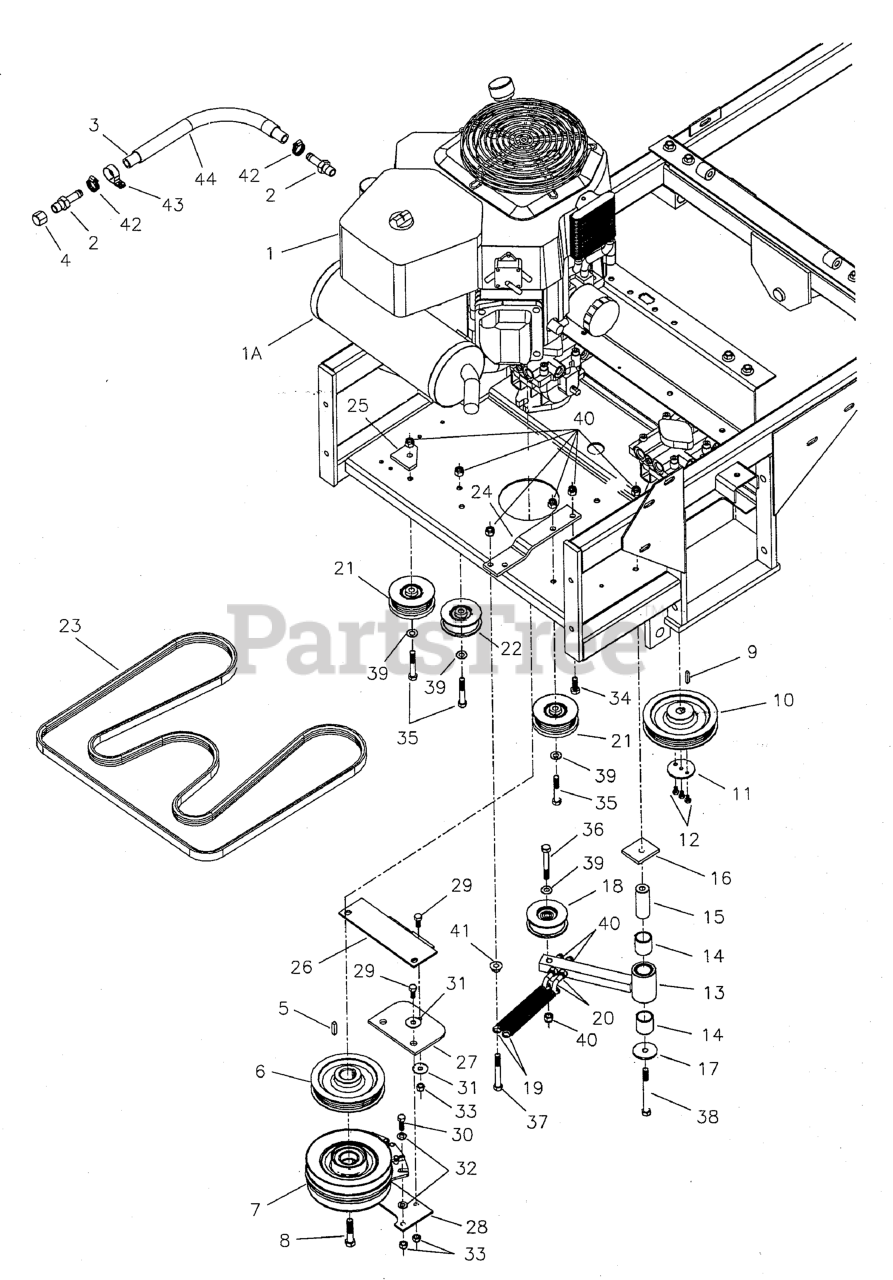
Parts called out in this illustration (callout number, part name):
1A	MUFFLER, Kohler
2	FITTING, 3/8NPT-1/2" Hose, Straight
3	HOSE, 16" Long
3	HOSE, 14"
4	CAP, 3/8 NPT
5	KEY, 1/4 SQ. X 1
6	PULLEY, Crankshaft
7	CLUTCH, Electric
7	CLUTCH, ISZKAV23
8	CRANKSHAFT BOLT, 7/16 x 2
8	CRANKSHAFT BOLT, 7/16 x 1-3/4
9	KEY, 5MM SQ. x 25MM w/ Round Ends
10	PULLEY, Pump Drive
11	WASHER, Pulley Retaining
12	BOLT, M6 x 10MM
13	IDLER ARM ASSEMBLY, Complete
14	BUSHING, Brass
15	SPACER, .39 X 1.00 X 2.55, SS
16	SPACER, Idler Pivot
17	WASHER, 3/8 x 1-3/4
18	HYDRO IDLER PULLEY ASSEMBLY
18	BEARING, BALL 11/16X1-9/16X15/32
18	SNAP RING, Internal
18	INSERT, Bearing
18	INSERT, Bearing, Shoulder
18	PULLEY, Backside Idler
19	SPRING, Extension
20	SCREW HOOK
21	IDLER PULLEY ASSEMBLY
21	BEARING, BALL 11/16X1-9/16X15/32
21	SNAP RING, Internal
21	INSERT, Bearing
21	INSERT, Bearing, Shoulder
21	PULLEY, Idler
22	BACKSIDE IDLER PULLEY ASSEMBLY
22	BEARING, BALL 11/16X1-9/16X15/32
22	SNAP RING, Internal
22	INSERT, Bearing
22	INSERT, Bearing, Shoulder
22	PULLEY, Backside Idler
23	BELT, Pump Drive
24	ANCHOR, Spring Idler
24	SPRING ANCHOR
25	SUPPORT, Pulley
26	MOUNT, Clutch Anchor
27	CLUTCH ANCHOR PAD
28	ANCHOR, Clutch
29	BOLT, 5/16-18 X 3/4 GD5
30	BOLT, 5/16-18 X 1 GD5 YZ
31	WASHER, 5/16" Fender
32	WASHER, 5/16" SAE
33	NUT, 5/16-18 Hex Nylon Lock
34	BOLT, 3/8-16 X 1" GD5 CZ
35	BOLT, 3/8-16 X 2-1/4" GD5 CZ
36	BOLT, 3/8-16 X 2-3/4" GD5 CZ
37	BOLT, 3/8-16 X 3" GD5 CZ
38	BOLT, 3/8-16 X 4" GD5 CZ
39	WASHER, 3/8 SAE
40	NUT, 3/8-16 HEX NYLON LOCK
41	NUT, 3/8-16 Hex Serrated Flange
42	CLAMP, #6 Hose
43	CLAMP, Vinyl
44	WIRE LOOM, 14"
44	WIRE LOOM, 12"
